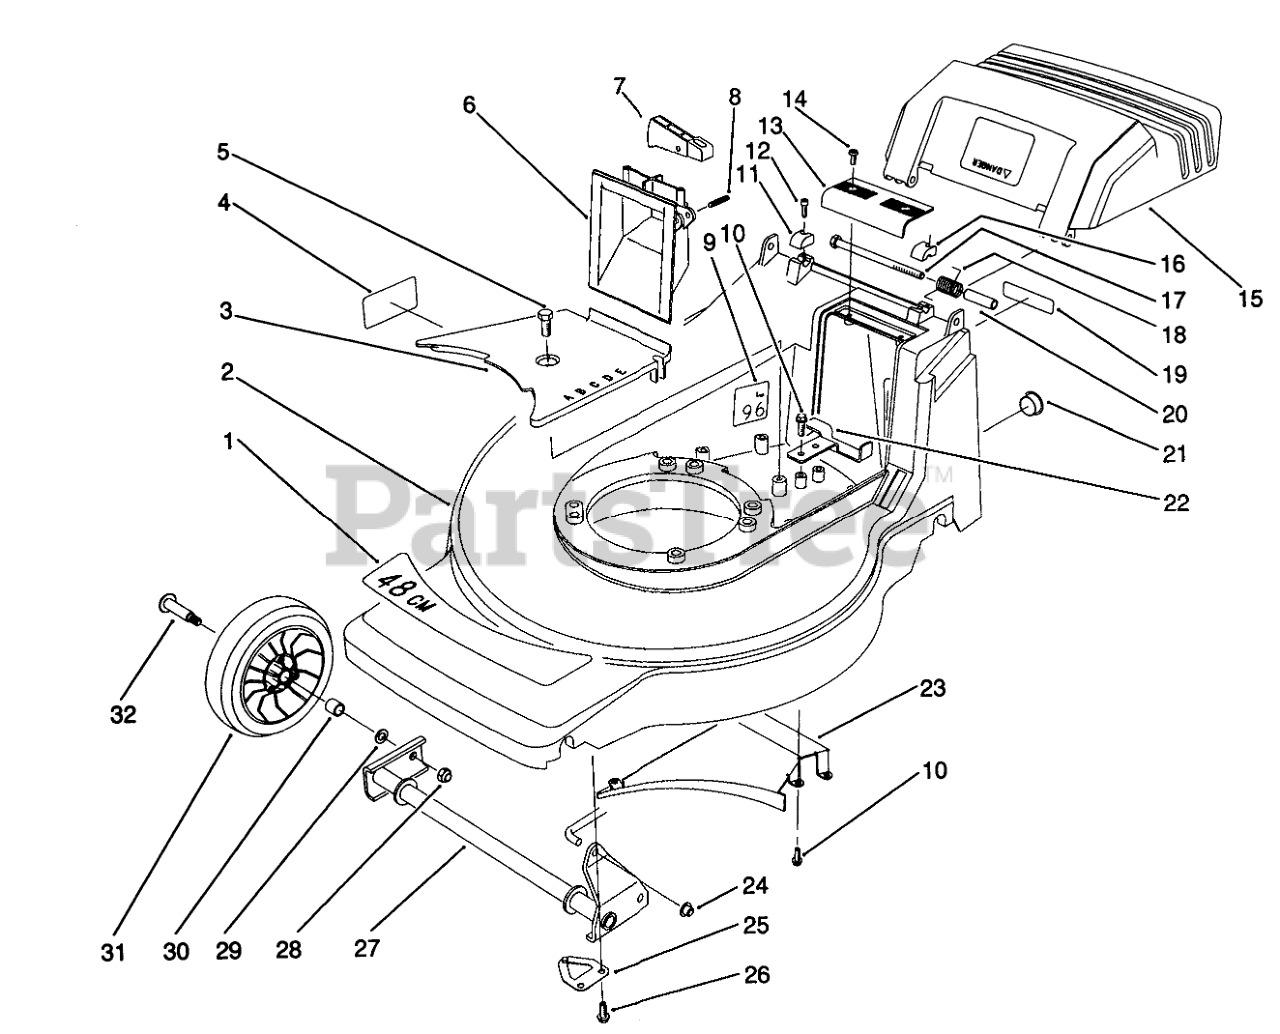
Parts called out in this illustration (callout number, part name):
1	DECAL - DECK
2	Housing-48cm
3	BELT COVER
4	Decal Danger
5	SCREW-HWHTF
6	GRIP - LOWER
7	TRIGGER - HOC
8	PIN-SPIRAL
9	Decal-Noise
10	SCREW-HWHTF
11	CAP-HINGE BOLT, RH
12	SCREW-HSH
13	GRIP-UPPER
14	SCREW-PPH, PLASTITE
15	Door-Discharge
16	CAP-HINGE BOLT, LH
17	SCREW-HH
18	DOOR SPRING
19	DECAL FRENCH REGUL.
20	SPACER-DOOR
21	DOME PLUG (DP-1000)
22	REAR BELT GUIDE
23	Ramp-Discharge
24	NUT-PUSH
25	SHAFT RETAINER ASM
26	Screw
27	FRONT PIVOT WA
28	NUT-HEX
29	WASHER
30	BUSHING
31	Wheel & Tire Assembly (Incl. Ref. #30)
32	BOLT-WHEEL
